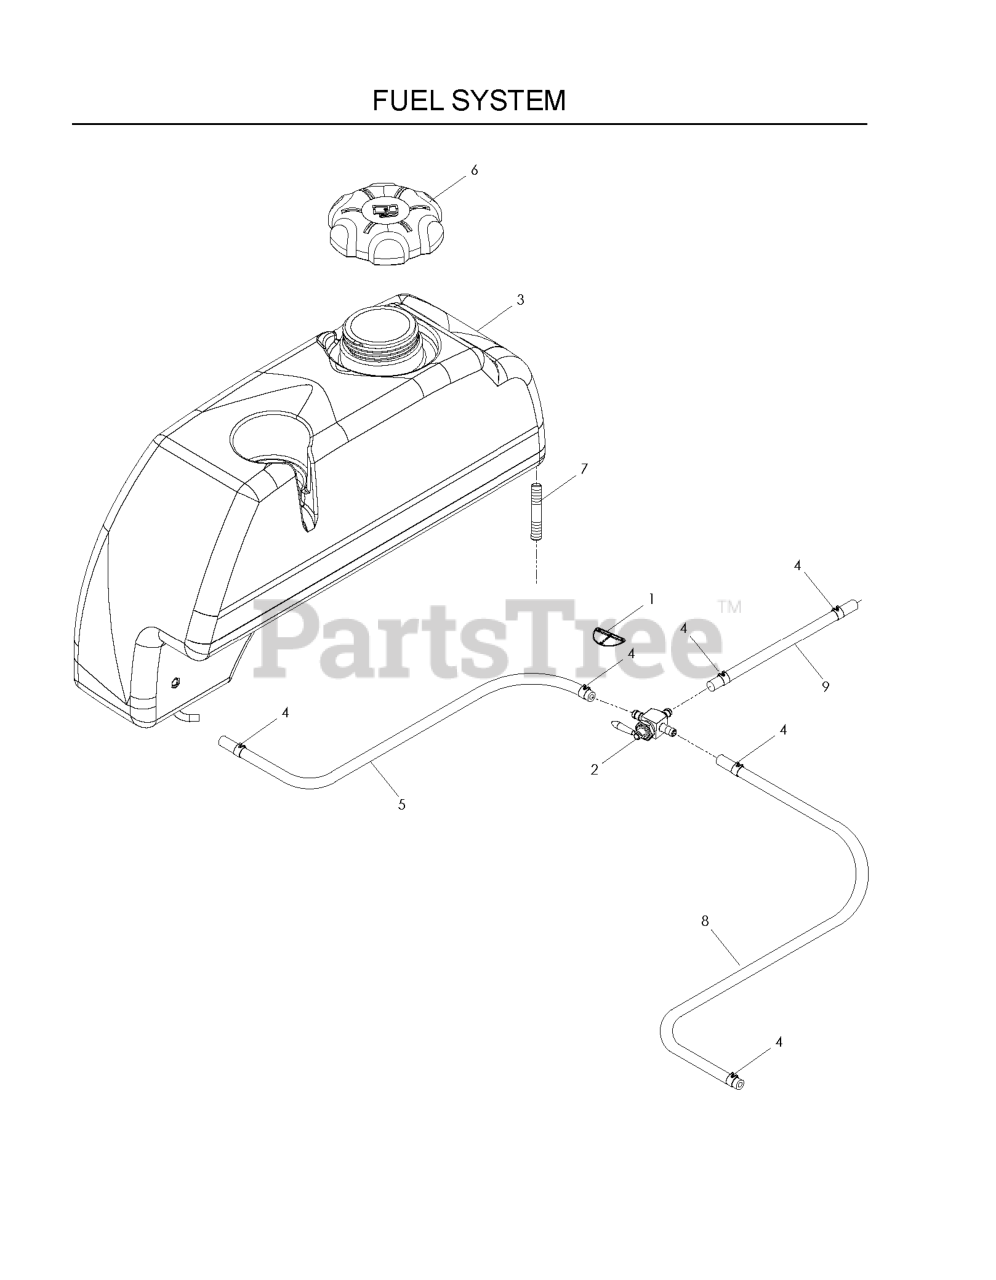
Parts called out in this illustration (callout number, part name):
1	DECAL, FUEL VALVE
2	FUEL VALVE
3	FUEL TANK RT
3	LEFT TANK W/CUP HOLDER
4	HOSE CLAMP
6	FUEL CAP, HTC
7	STUD, 5/16C
9	FUEL LINE 13"
